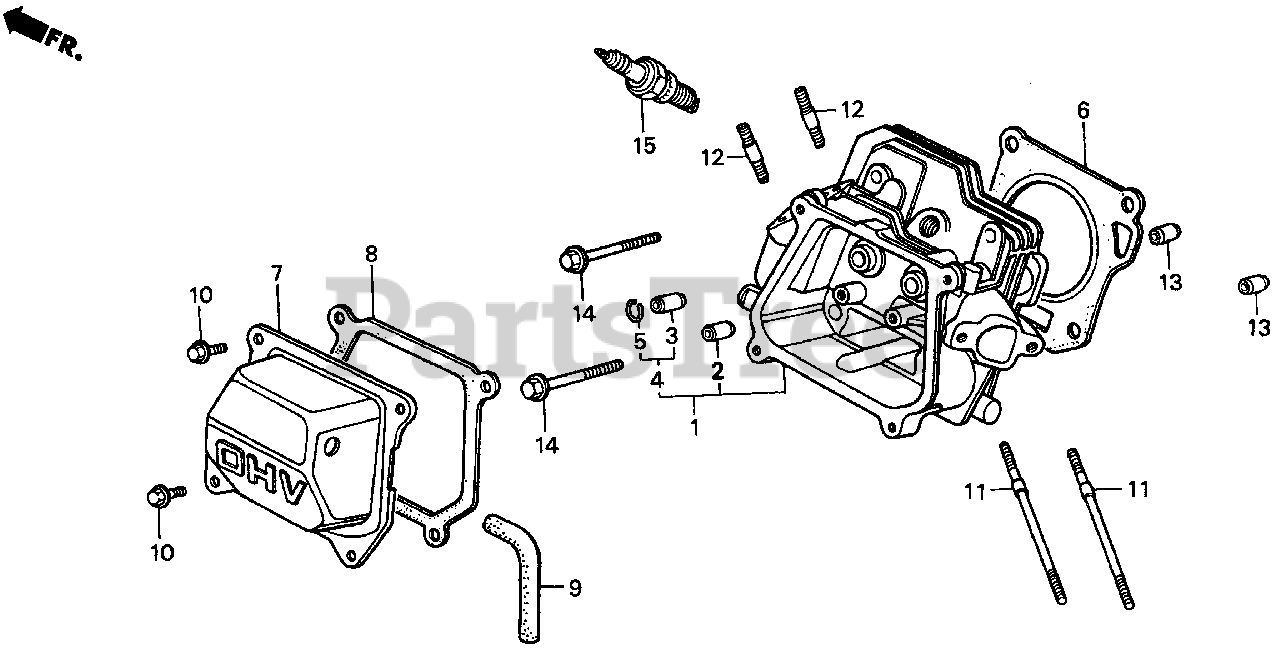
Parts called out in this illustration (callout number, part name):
1	CYLINDER HEAD
2	GUIDE, VALVE (OS)
4	GUIDE, EX. VALVE (OS)
5	CLIP, VALVE GUIDE
6	GASKET, CYLINDER HEAD
7	COVER, HEAD
8	GASKET, CYLINDER HEAD COVER
9	TUBE, BREATHER
10	BOLT, FLANGE (6X12) (CT200)
11	BOLT, STUD (6X109)
12	BOLT, STUD (8X32)
13	PIN A, DOWEL (10X16)
14	BOLT, FLANGE (8X60)
15	SPARK PLUG (BPR5ES) (NGK)
15	SPARK PLUG (W16EPR-U) (DENSO)
